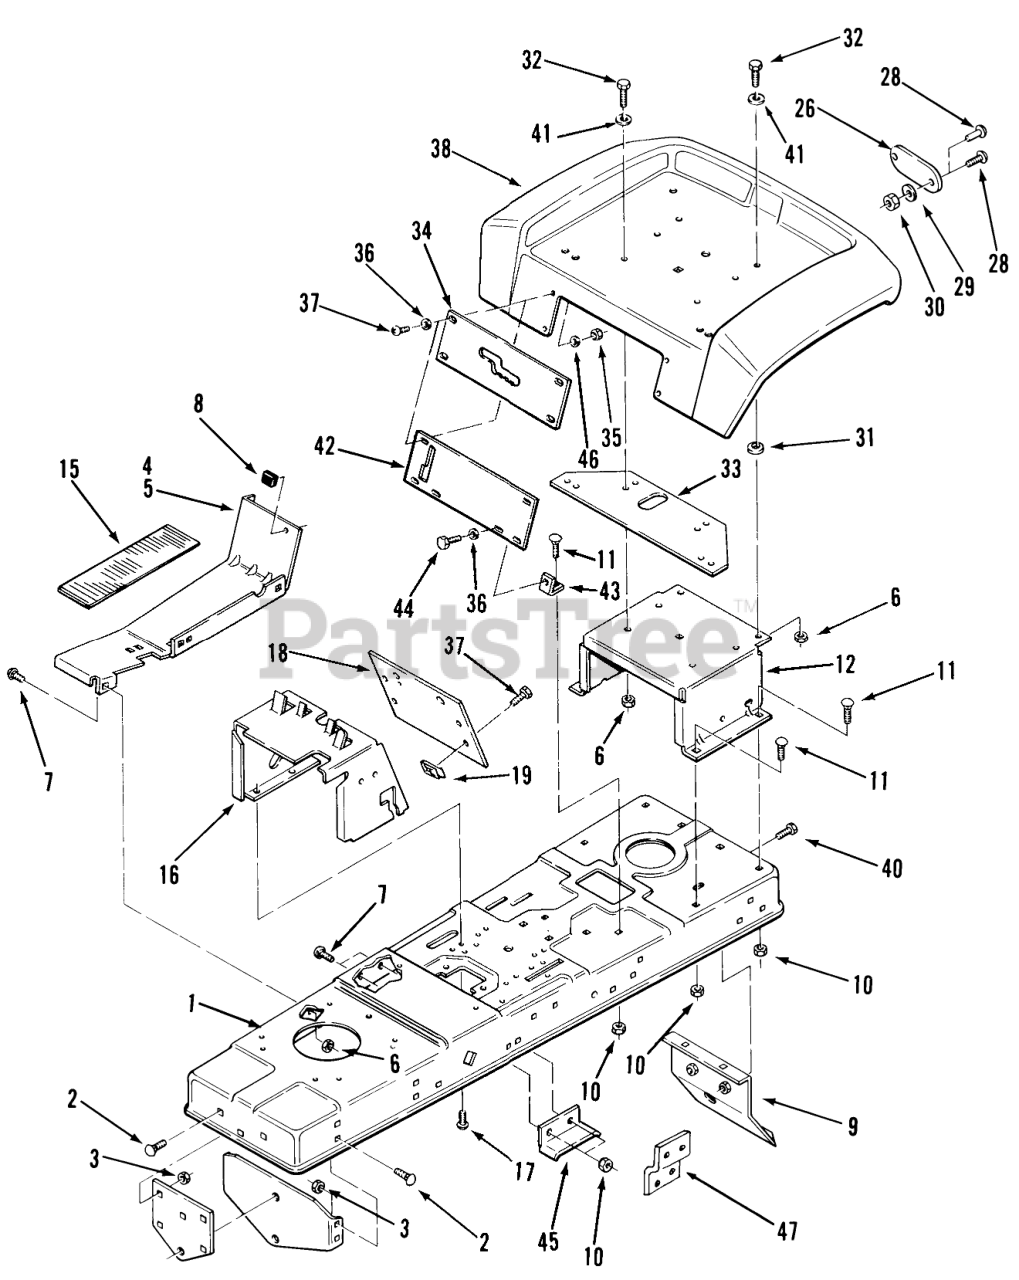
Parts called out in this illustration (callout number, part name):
1	Frame 208-3, 211-3, 211-5
2	Bolt
3	Nut
4	RH FOOTREST R
5	Footrest LH
6	Nut
7	Bolt-Carriage
8	BUMPER
9	Hitch-Drawar
10	Nut
11	Bolt
12	SUPPORT-SEAT R
15	PAD-FOOTREST
16	Hoodstand
17	SCREW
18	Hoodstand Plate 208-3, 211-3 Only
26	Reflector
28	Poprivet
29	Lockwasher
30	Nut
31	WASHER
32	Bolt
33	PLATE-SEAT R
34	PLATE SHIFT R
35	Nut
37	Screw
38	FENDER R
40	Bolt
41	WASHER 5/16 SAE
42	PLATE FRT FENDER R
43	BRACKET FENDER
44	Bolt
45	Belt Support
46	Washer
47	BRKT SWITCH BRAKE R
